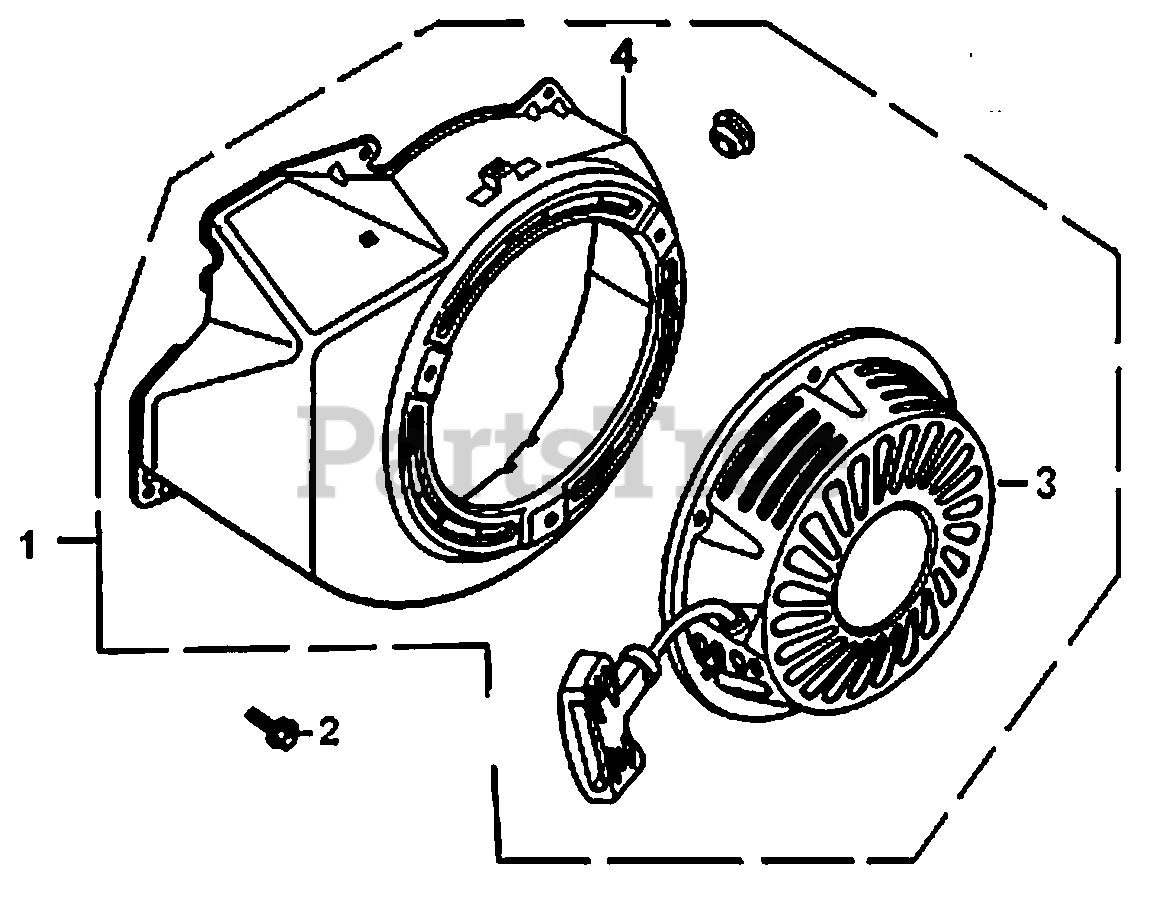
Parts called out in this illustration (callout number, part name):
1	STARTER ASSY.
2	BOLT, FLANGE, M6X12
3	ASSY, RECOIL STARTER
4	BLOWER HOUSING, RECOIL STARTER
